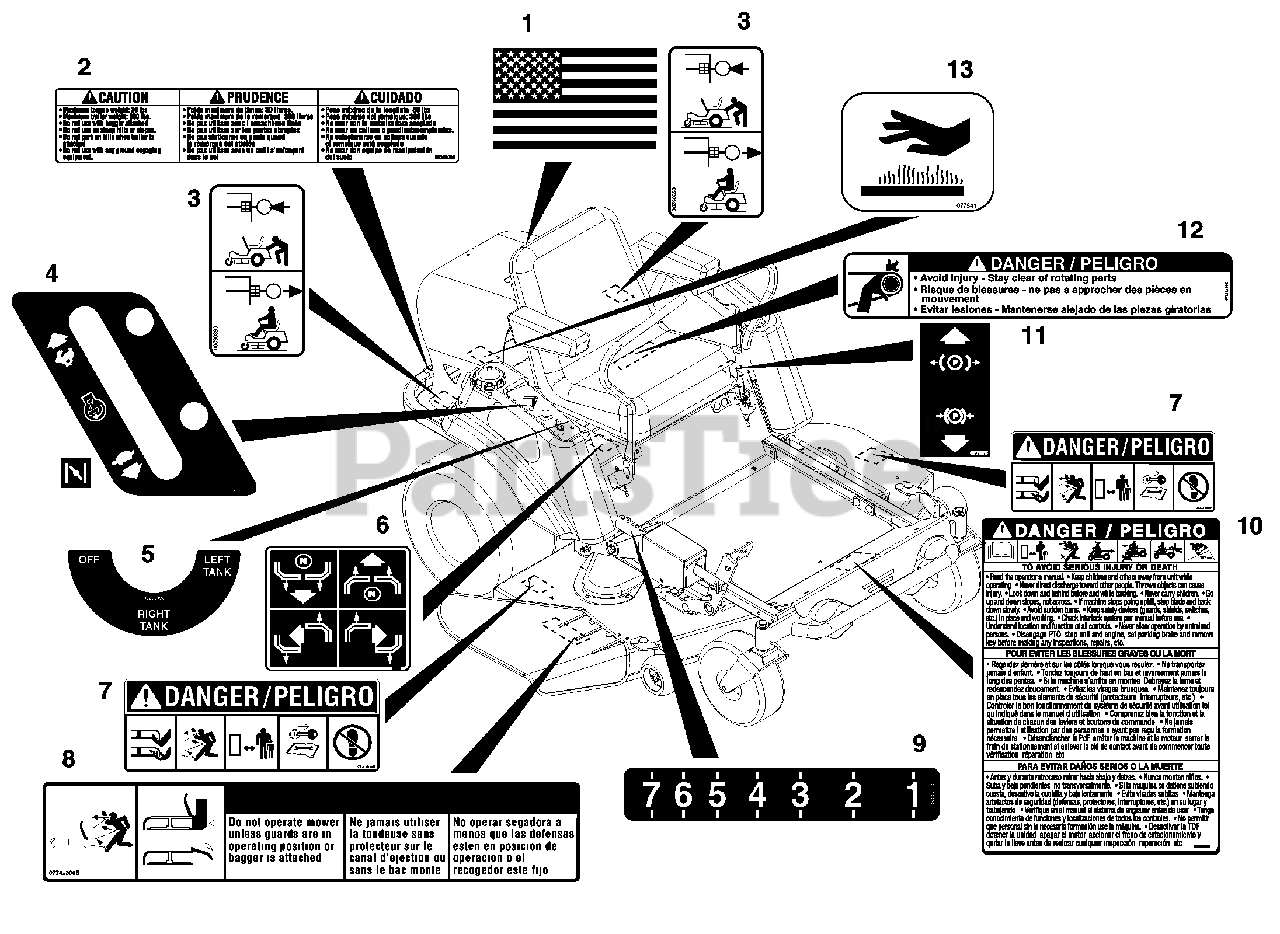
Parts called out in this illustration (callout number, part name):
1	DECAL, AMERICAN FLAG
2	DECAL, TRAILER HITCH
3	DECAL, TRANSMISSION DISCONNECT
4	DECAL, SPEED CONTROL
5	DECAL, FUEL VALVE
6	DECAL, INSTRUCTIONAL-STEERING
7	DECAL, MOWER PAN DANGER
8	DECAL, WARNING
9	DECAL CUT HEIGHT
10	DECAL, DANGER BILINGUAL
11	DECAL, PARKING BRAKE LEVER
12	DECAL- DANGER
13	DECAL, HOT SURFACE
